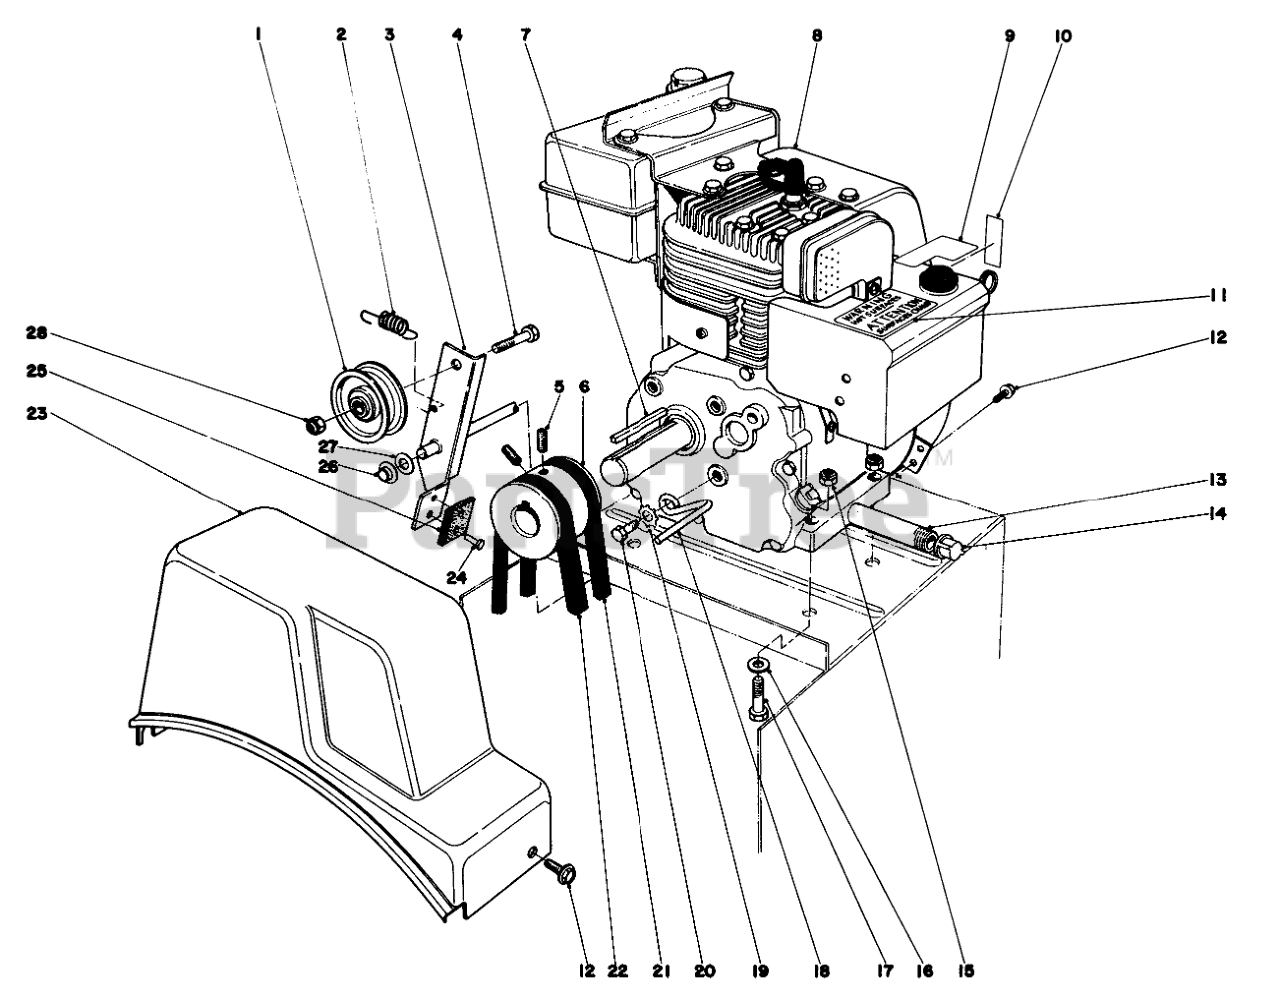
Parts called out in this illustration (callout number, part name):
1	PULLEY-IDLER
2	EXTENSION SPRING
3	Auger Clutch (Incl. Ref. #24 & #25)
4	SCREW-HH
5	Screw-Set
6	ENGINE PULLEY
8	Engine
9	CHOKE & PRIMER DECAL
10	DECAL THROTTLE
11	Decal Hot Surface Warning
12	SCREW
13	PIPE NIPPLE
14	CAP-PIPE
15	NUT-LOCK, NI
16	WASHER-FLAT
17	SCREW-HH
18	RETAINER-BELT
19	WASHER-LOCK
20	SCREW-HH
21	V BELT-3L, TRACTION
22	V-BELT (29.50 INCH)
23	COVER-BELT
24	.185 DIA X .375 RT +
25	BRAKE PAD
26	RETAINER-PUSH ON
27	WASHER-FLAT
28	NUT-LOCK, NI
